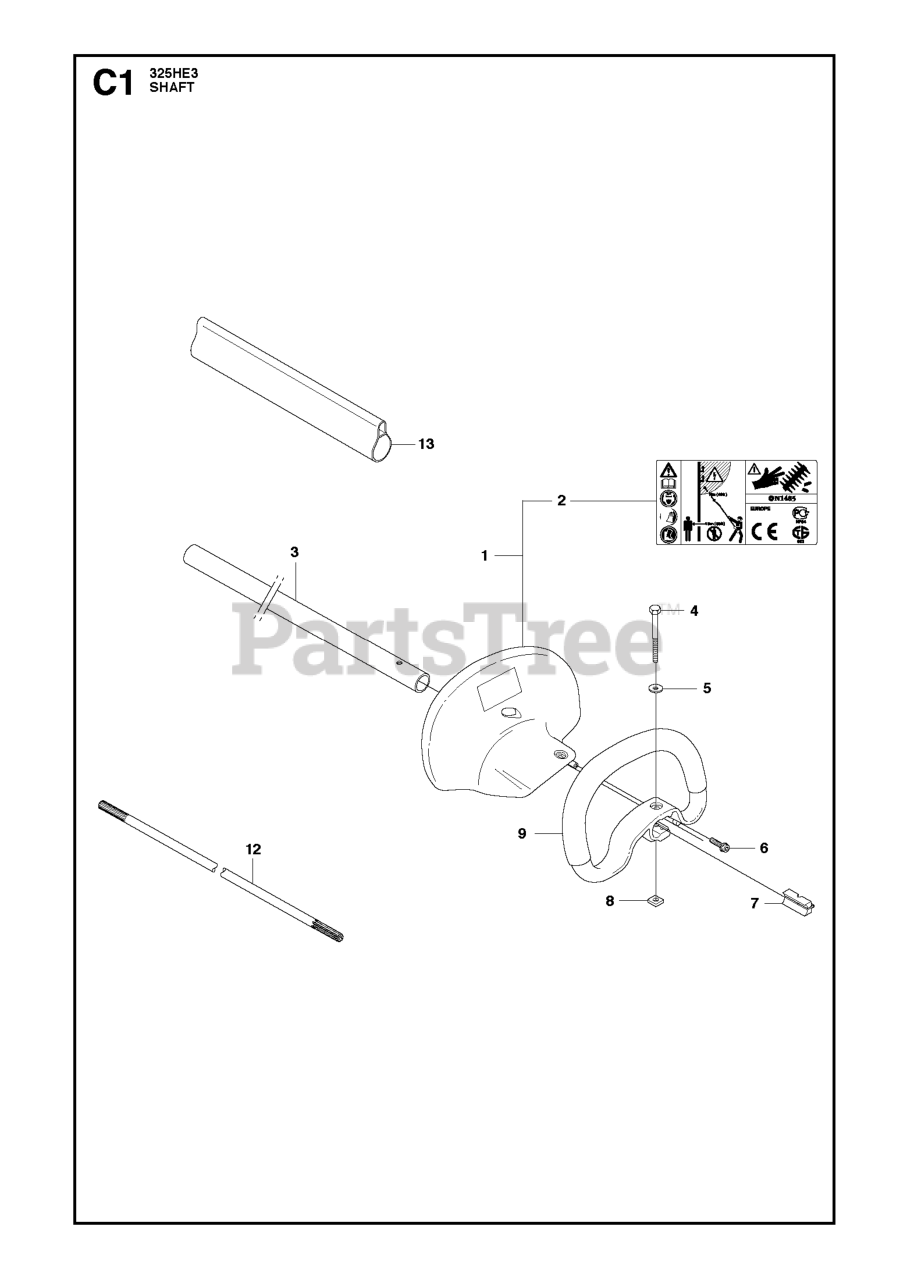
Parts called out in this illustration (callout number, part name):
1	HAND GUARD
2	LABEL WARNING
5	WASHER - M6
7	SPACER PLASTIC
12	DRIVESHAFT 525HF3S
